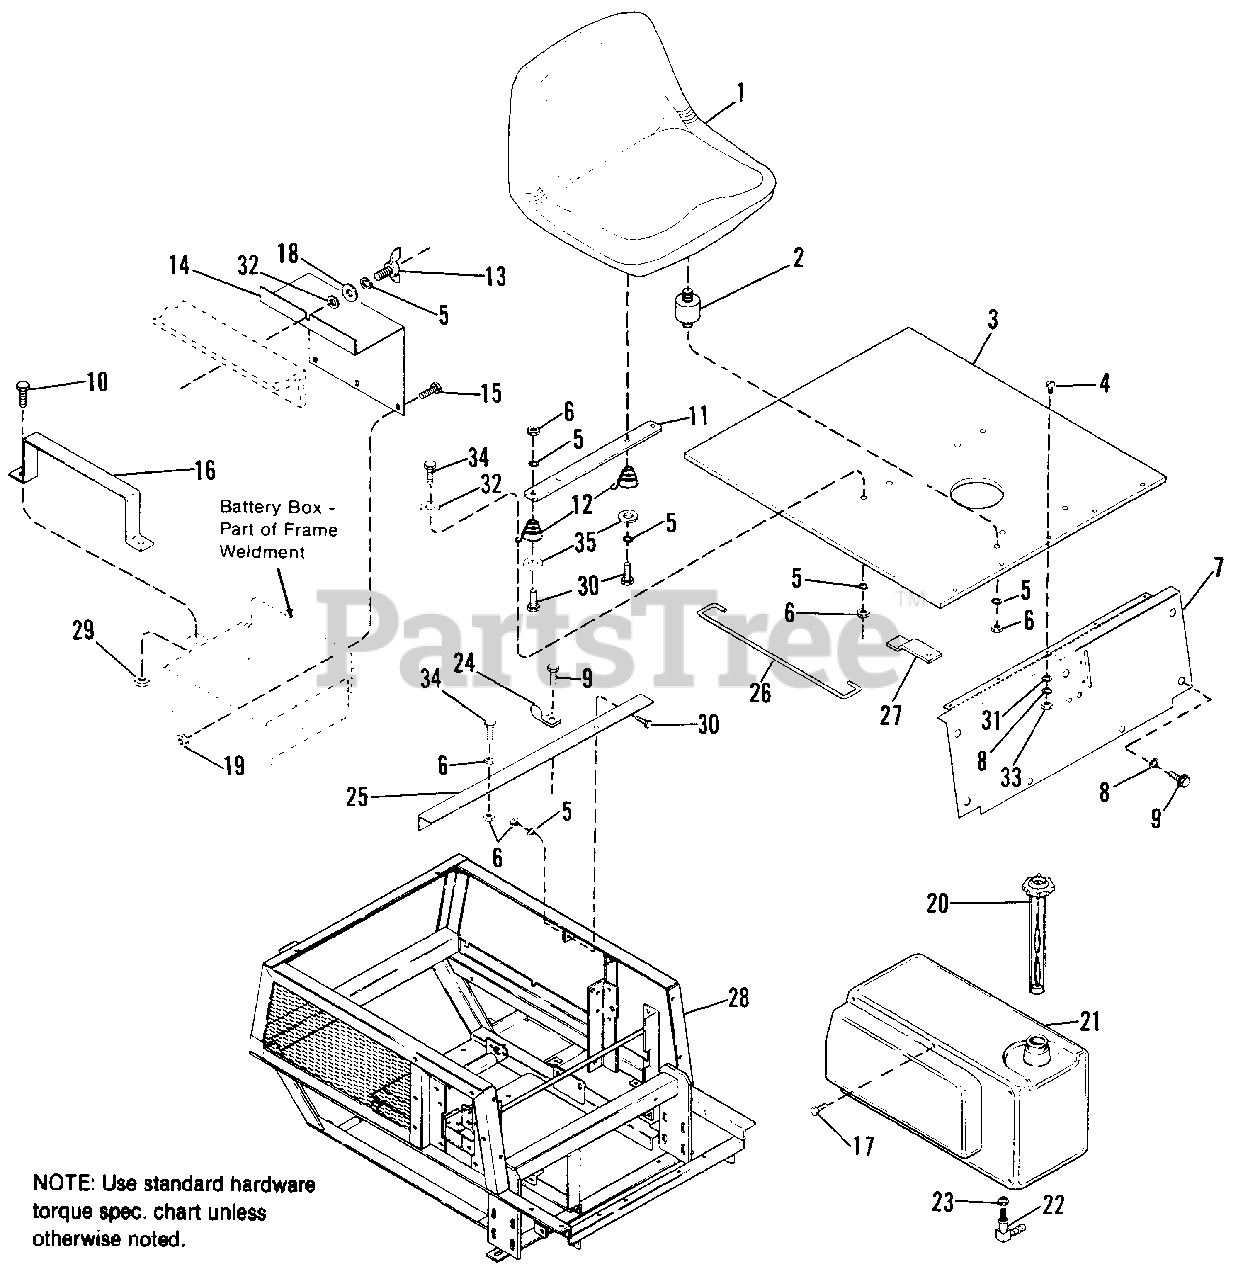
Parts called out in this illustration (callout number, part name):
3	SEAT PAN ASSY.
4	SCREW, Pan Head Phillips, #10-24 x 1
5	LOCKWASHER, Spring 5/16
6	NUT, Hex, 5/16-18
7	FRONT ASSY.
8	LOCKWASHER, Spring, #10
9	SCREW, Taptite, 1/4-20 x 5/8
10	CAPSCREW, Hex, 5/16-18 x 2-1/2
11	BAR, Spring
12	SPRING, Seat
13	SCREW, Wing, 5/16-18 x 3/4
14	COVER, Battery
15	SCREW, Round Hd., #10-32 x 3/8
16	STRAP, Battery
17	SCREW, Hex, Whizlock, 5/16-18 x 1/2
18	WASHER, 1" O.D.
19	LOCKNUT, Hex, #10-32
20	CAP, Fuel Tank w/ Gauge
21	FUEL TANK ASSY.
22	ELBOW, Fuel Tank
23	BUSHING, Fuel Tank
25	SUPPORT, Seat
26	ROD, Support
27	BRACKET, Latch
28	FRAME ASSY.
29	NUT, Hex, Centerlock, 5/16-18
30	CAPSCREW, Hex, 5/16-18 x 1
31	WASHER, Plain
32	WASHER, Plain, 3/4" O.D.
33	NUT, Hex, #10-24
34	CAPSCREW, Hex, 5/16-18 x 3/4
35	WASHER, Plain
